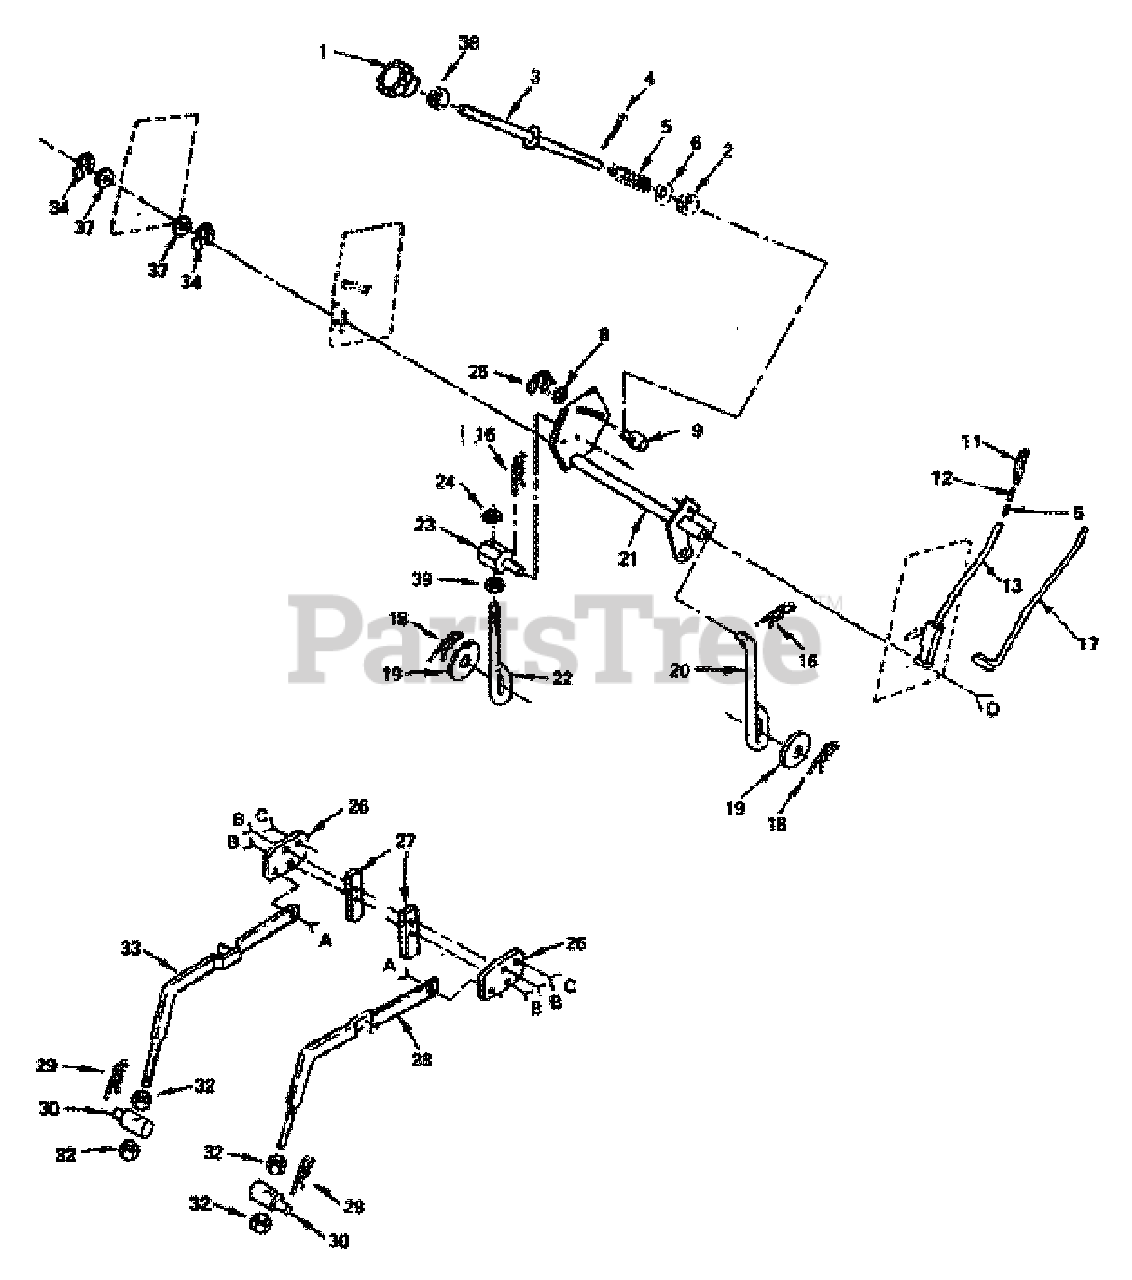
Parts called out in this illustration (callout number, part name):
1	Knob, Depth Adjustment
3	Rod - Adjust - Lid
5	Spring
6	Washer 13/32 x 5/8 x 16 Ga.
10	Bob - Shoulder 3/8 - 16
11	Grip Handle
12	Plunger- Lever
13	Lever - Lift
14	Spring Washer
16	Retainer - Spring
17	Rod- Lever
18	Retainer Spring
19	Washer 17/32 x 15/16 x 16 Ga.
20	Link - Lift
21	Shaft- Lift
22	Link Lift - Adjust
23	Trunnion - Lid
26	Bracket - Suspension
28	Arm- Suspension R.H.
29	Retainer- Spring
30	Lift- Lower
33	Arm - Suspension - L.H.
36	Bolt- Carriage 3/8- 16 x 3/4
37	Washer 29/32 x 1 - 1/4 x 16 Ga.
38	Nut - Special
39	Nut, Hex Jam 3/8 x 16 UNC
41	Button.Plunger
42	Scale.Height.Indicator
43	Pointer.Height.Indicator
